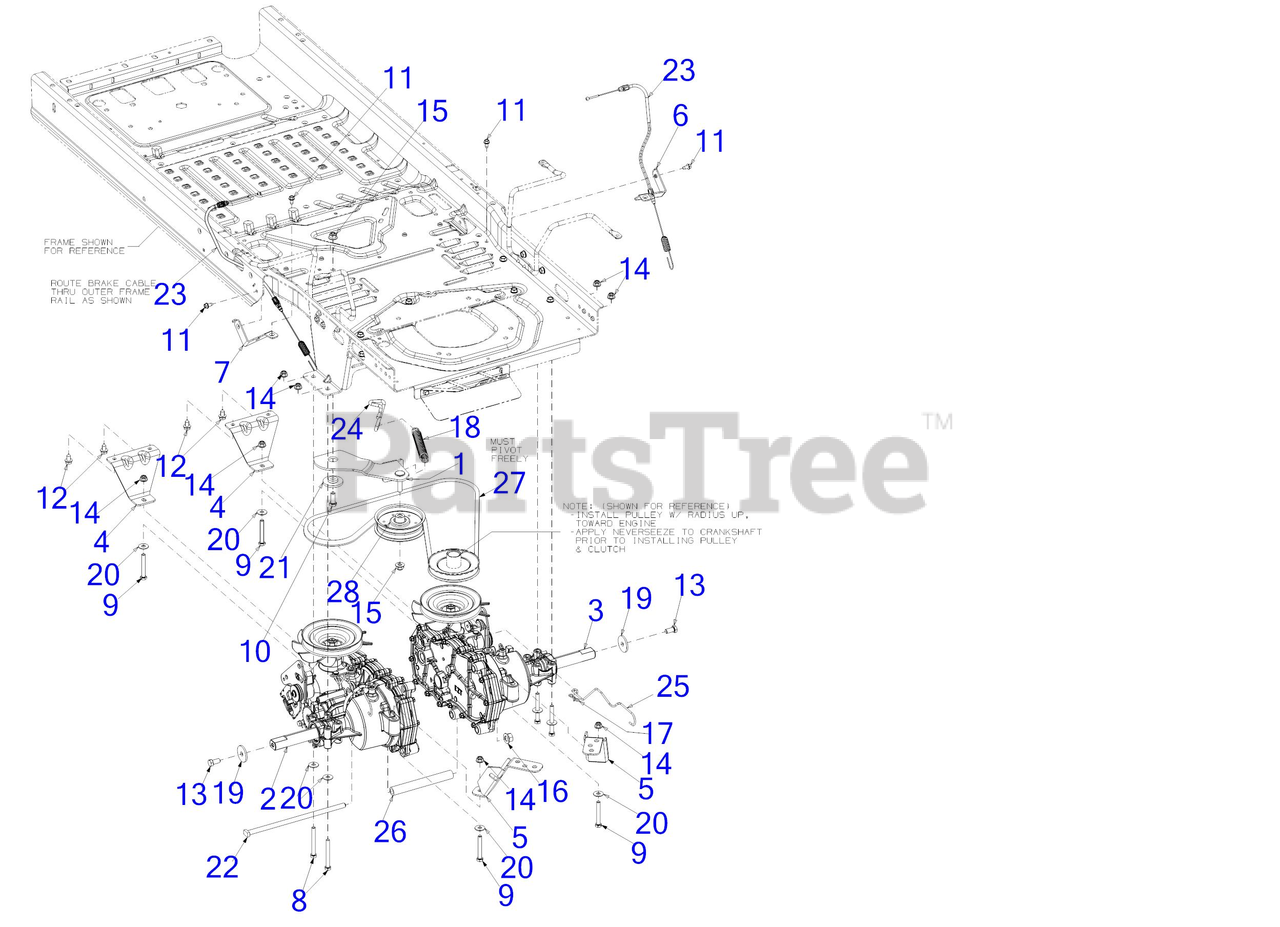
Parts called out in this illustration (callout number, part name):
1	IDLER BRACKET ASSEMBLY
2	HYDRO TRANSMISSION ASSEMBLY (LH)
3	HYDRO TRANSMISSION ASSEMBLY (RH)
4	TRANSMISSION MOUNTING BRACKET
8	HEX SCREW 5/16-18 x 2.75
9	HEX SCREW 5/16-18 x 2.25 GR5
10	SCREW 3/8-16 x 1 GR5
11	SCREW 1/4-20 X.500
12	SCREW 5/16-18 x .625
13	SCREW 3/8-16 x .75 GR 5
14	FLANGE LOCK NUT 5/16-18
16	FLANGE LOCK NUT
17	BOW TIE COTTER PIN 1/4-5/16
18	EXTENSION SPRING .75 DIA X 5.87
19	FLAT WASHER .390x1.500x.134
20	FLAT WASHER
21	SHOULDER SPACER
22	SUPPORT TUBE ROD
23	PARK BRAKE CABLE
24	IDLER SPRING HOOK
25	HYDRO BYPASS ROD
26	SUPPORT TUBE
27	DRIVE BELT A X 62.24
28	FLAT IDLER PULLEY 4.0 DIA
